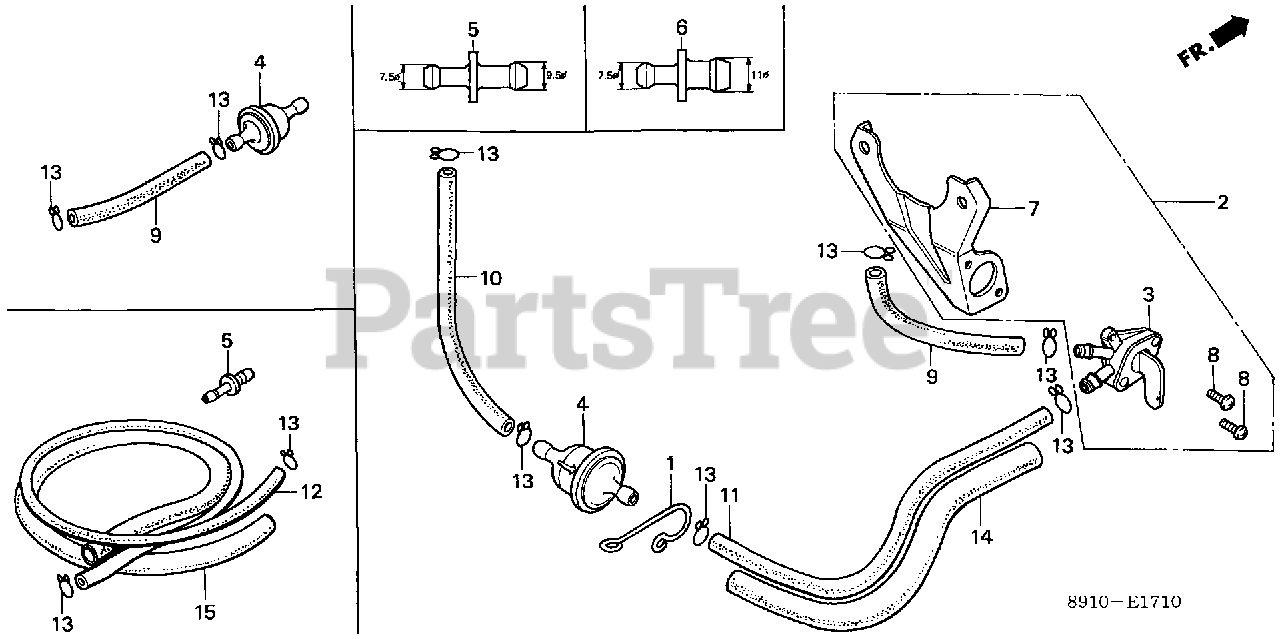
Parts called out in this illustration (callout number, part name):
12	BULK HOSE, FUEL (5.5X3000)
13	CLIP, TUBE (B10)
15	BULK HOSE, VACUUM (11X1000)
